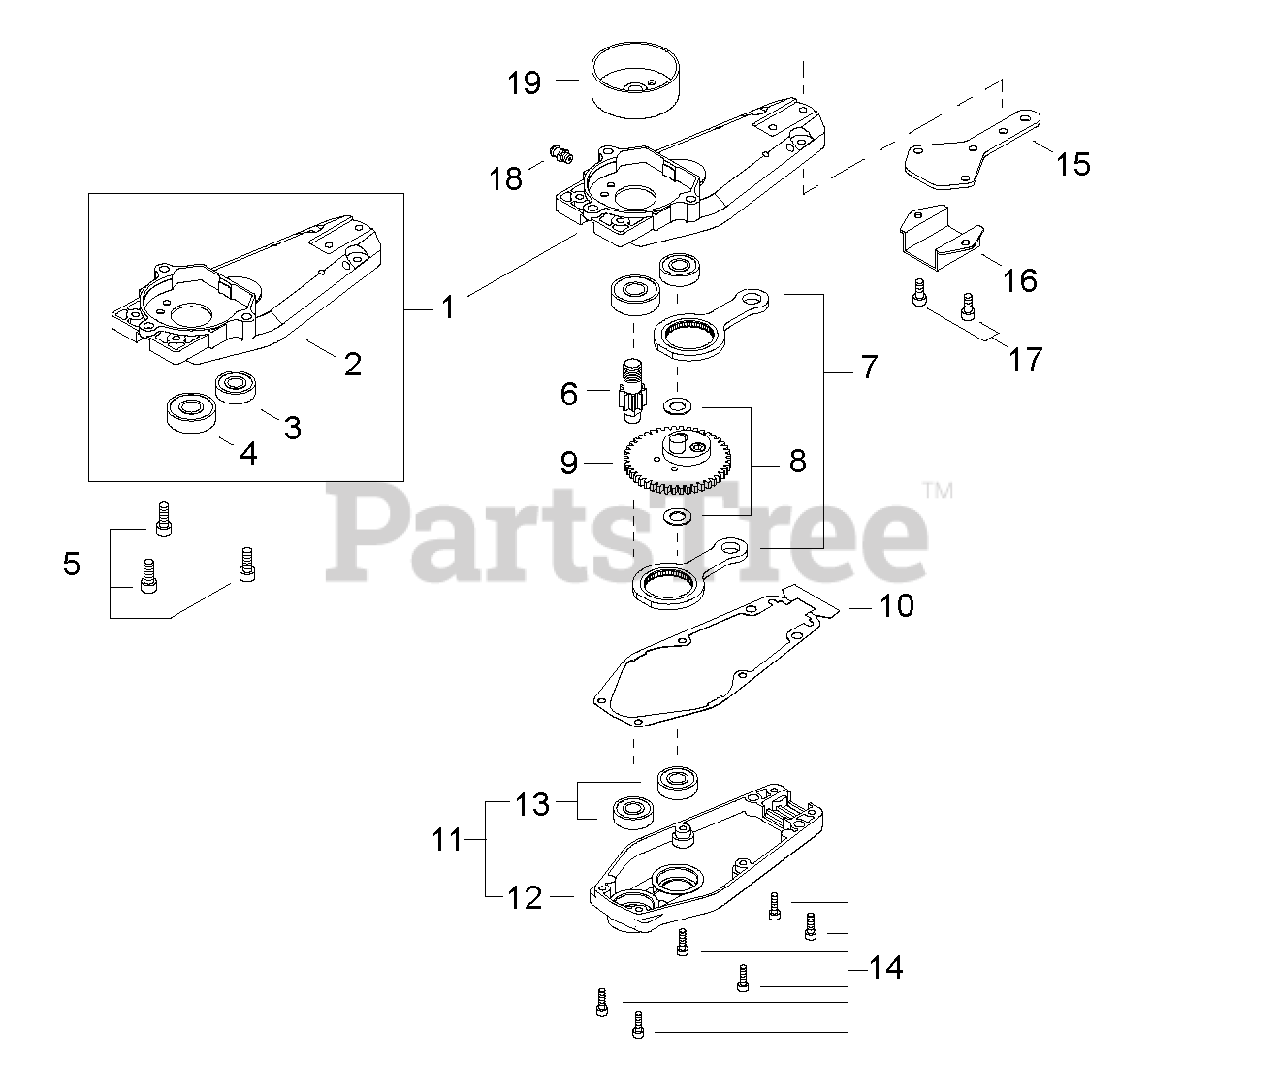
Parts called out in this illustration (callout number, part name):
1	GEAR CASE ASSY
2	CASE, GEAR
3	BEARING, BALL - 6000ZZ
4	BEARING, BALL - 6201
5	SCREW - 6X16
6	SHAFT, PINION
7	ROD, CONNECTING
8	WASHER - 10
9	CAM GEAR ASSY
10	GASKET, GEAR CASE
11	GEAR CASE LID ASSY
12	LID, GEAR CASE
13	BEARING, BALL - 6000ZZ
14	SCREW - 4X14
16	GUIDE, BLADE
17	SCREW - 5X12
18	FITTING, GREASE
19	DRUM, CLUTCH
